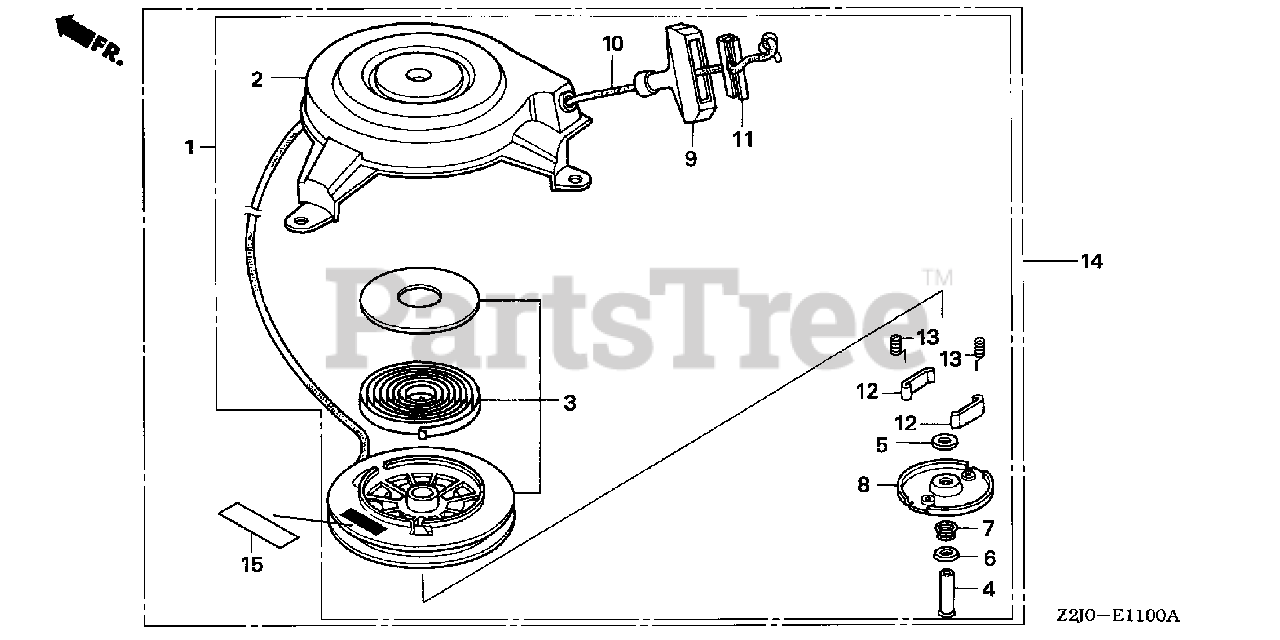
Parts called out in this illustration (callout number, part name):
1	STARTER ASSY., RECOIL
2	HOUSING ASSY. (NA USE ALT:28400-ZG9-803)
3	PULLEY & SPRING ASSY.
4	PIN, CENTER
5	PLATE A, FRICTION
6	PLATE B, FRICTION
7	SPRING, FRICTION
10	ROPE, RECOIL STARTER
11	HANDLE, REINFORCEMENT
13	SPRING, DOG
